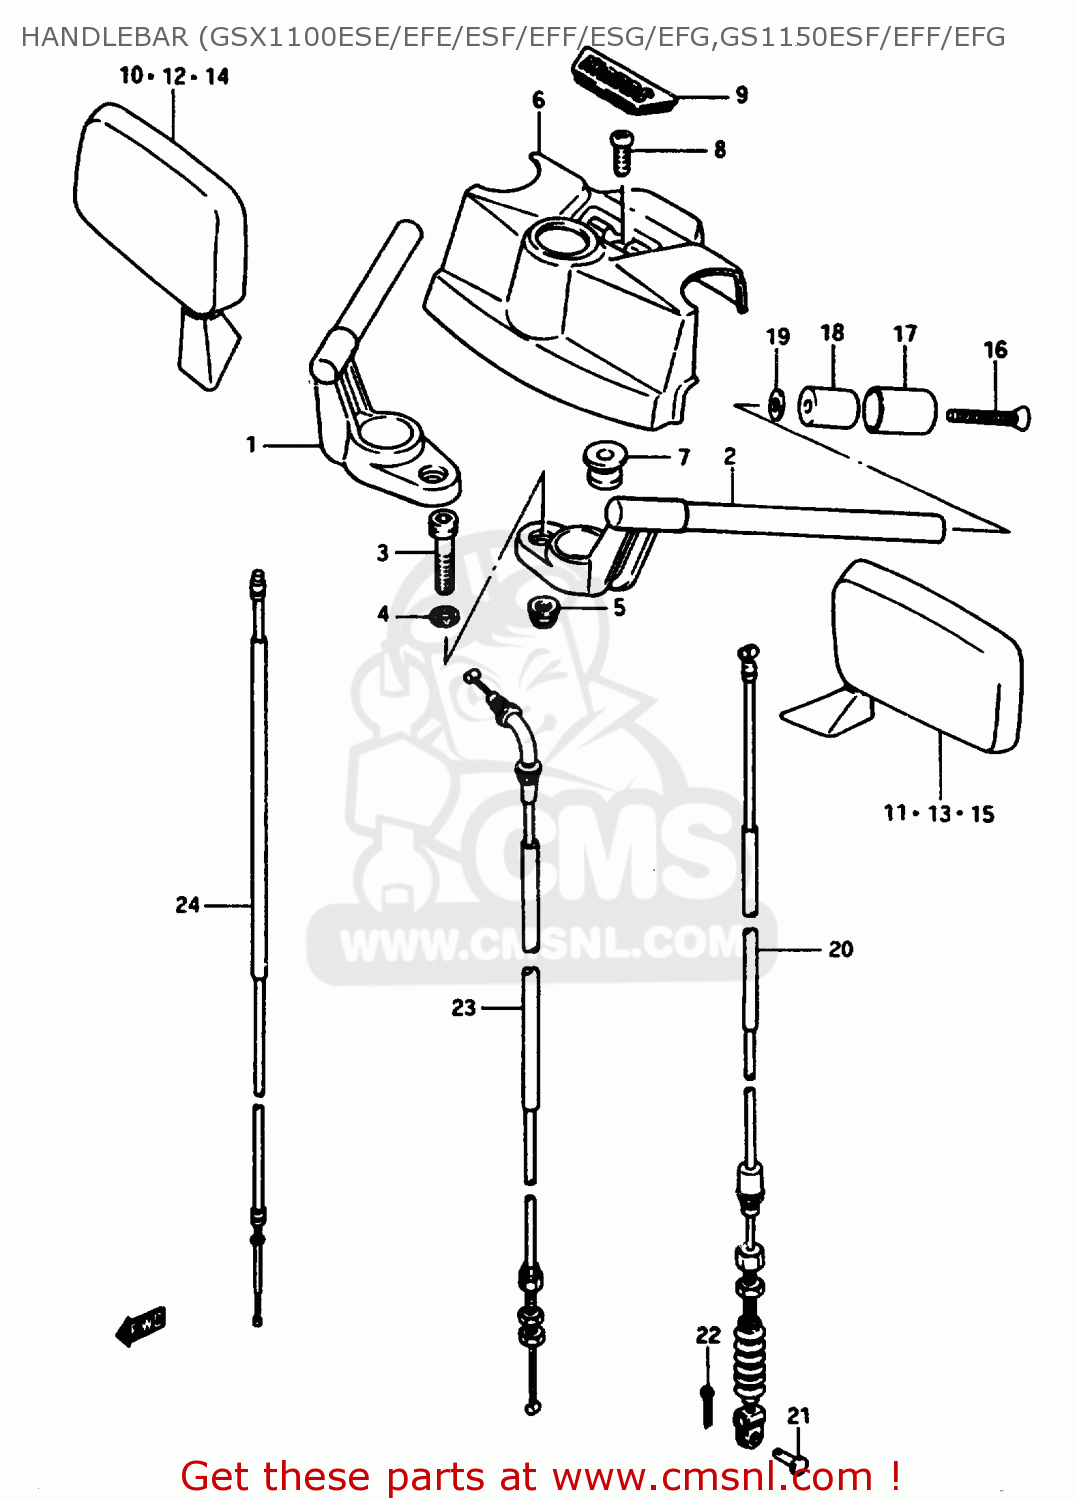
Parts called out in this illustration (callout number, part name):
1	HANDLEBAR, RH
2	HANDLEBAR, LH
3	BOLT(10X50)
4	WASHER
5	NUT 10MM
6	PAD,HANDLE
7	CUSHION,METER BRACKET
8	SCREW
9	CAP,HANDLE PAD
10	MIRROR ASSEMBLY,RIGHT
11	MIRROR ASSEMBLY,LEFT
12	MIRROR ASSY,RR VIEW,R
13	MIRROR ASSY,RR VIEW,L
14	MIRROR, REAR VIEW RH
15	MIRROR, REAR VIEW LH
16	SCREW
17	CAP,BALANCER
18	BALANCER,HANDLE
19	SPACER,BALANCER
20	CABLE ASSY,CLUTCH
21	PIN(L:15)
22	PIN
23	CABLE, THROTTLE
24	CABLE COMP,STARTER
